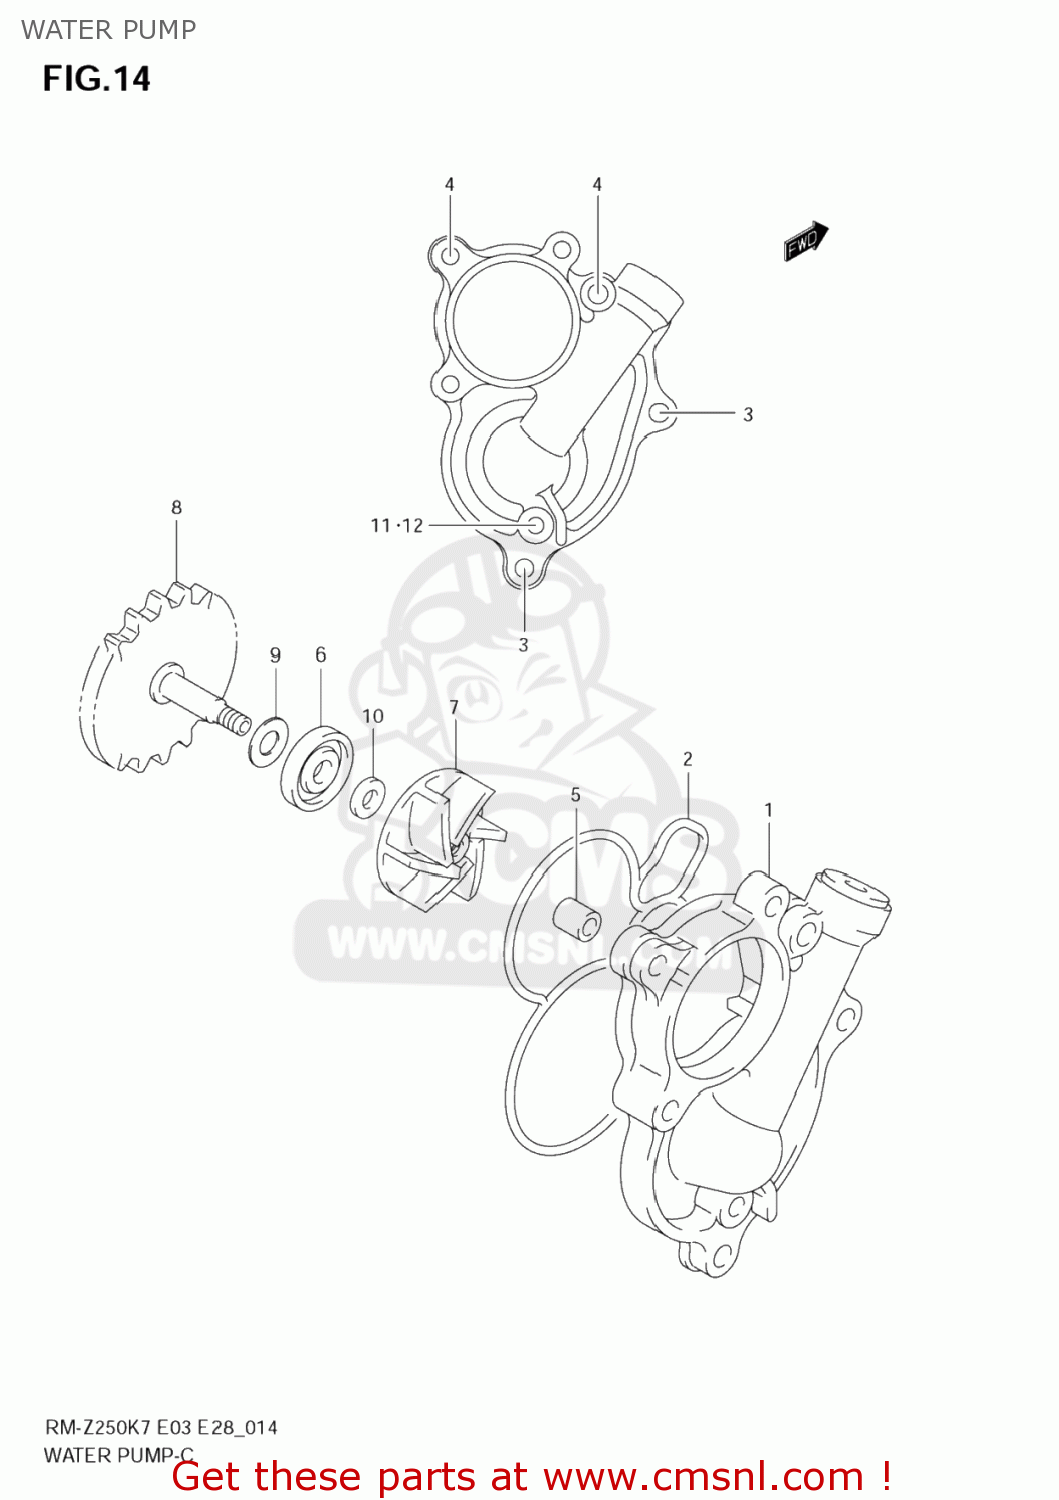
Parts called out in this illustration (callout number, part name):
1	CASE,WATER PUMP
2	O RING,WATER PUMP CASE
3	BOLT
4	BOLT
5	PIN
6	SEAL,WATER PUMP OIL
7	IMPELLER,WATER PUMP
8	SHAFT COMP,WAT
9	SHIM(8X18X0.5)
10	SHIM(6X14X1)
11	BOLT
12	GASKET(6.2X11X1).2 (NAS)
